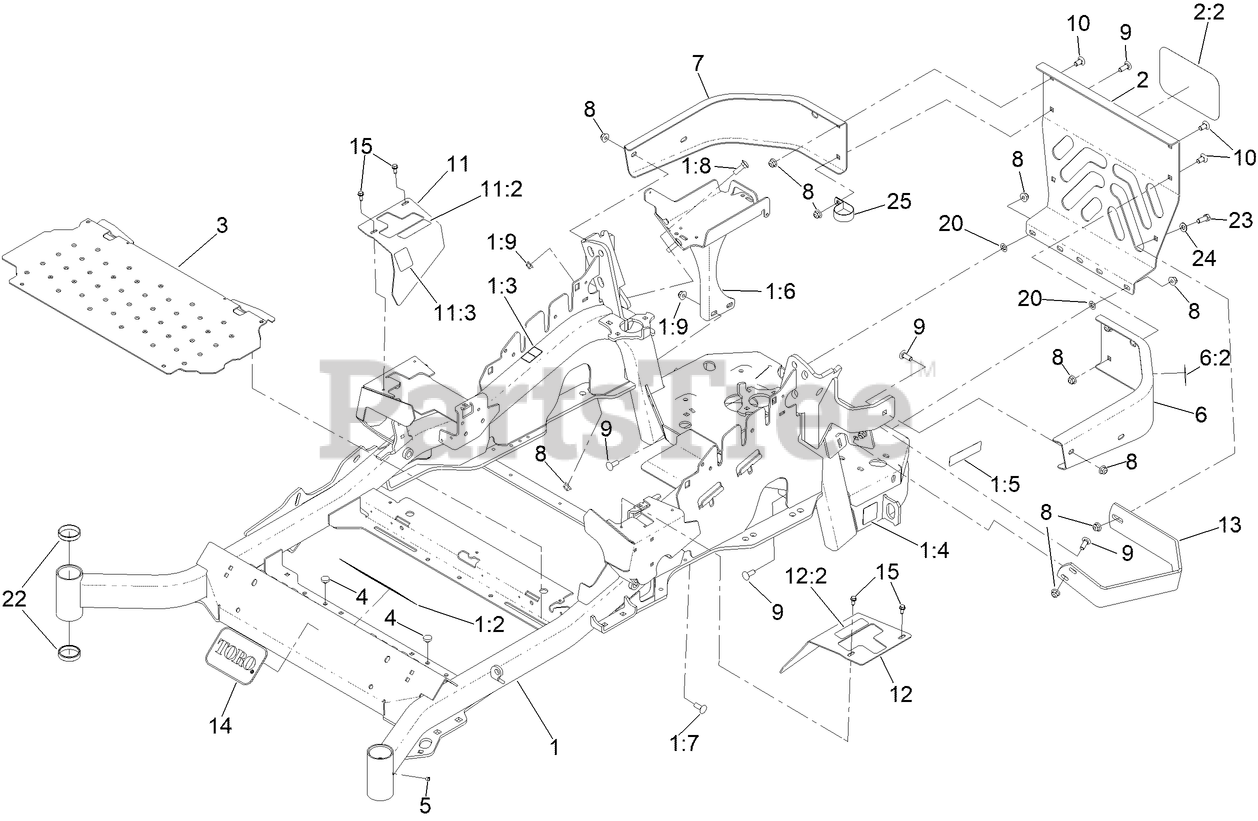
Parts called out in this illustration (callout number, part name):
1	MAINFRAME SERVICE ASM - 60
1:2	DECAL-DANGER
1:3	DECAL-WARNING
1:4	DECAL-HAZARD, PINCHED FINGER
1:5	DECAL-ARRESTOR, SPARK
1:6	BATTERY MOUNT ASM
1:7	SCREW-CARR
1:8	BOLT-CARR
1:9	NUT-HF, NI
2	REAR GUARD ASM
2:2	DECAL
3	FLOORPAN
4	BUMPER
6	LH BUMPER ASM
6:2	DECAL-WARNING
7	BUMPER-RH
8	NUT-HF, NI
9	SCREW-CARR
10	SCREW-CARR
11	RH MOTION CONTROL COVER ASM
11:2	DECAL-CONTROL, MOTION
11:3	DECAL-PARK BRAKE, CE
12	LH MOTION CONTROL COVER ASM
12:2	DECAL-CONTROL, MOTION
13	GUARD-MUFFLER
14	DECAL
15	SCREW-HWH
20	NUT-PUSH
22	CUP-BEARING
23	SCREW-HH
24	WASHER-FLAT
25	CLAMP-R
